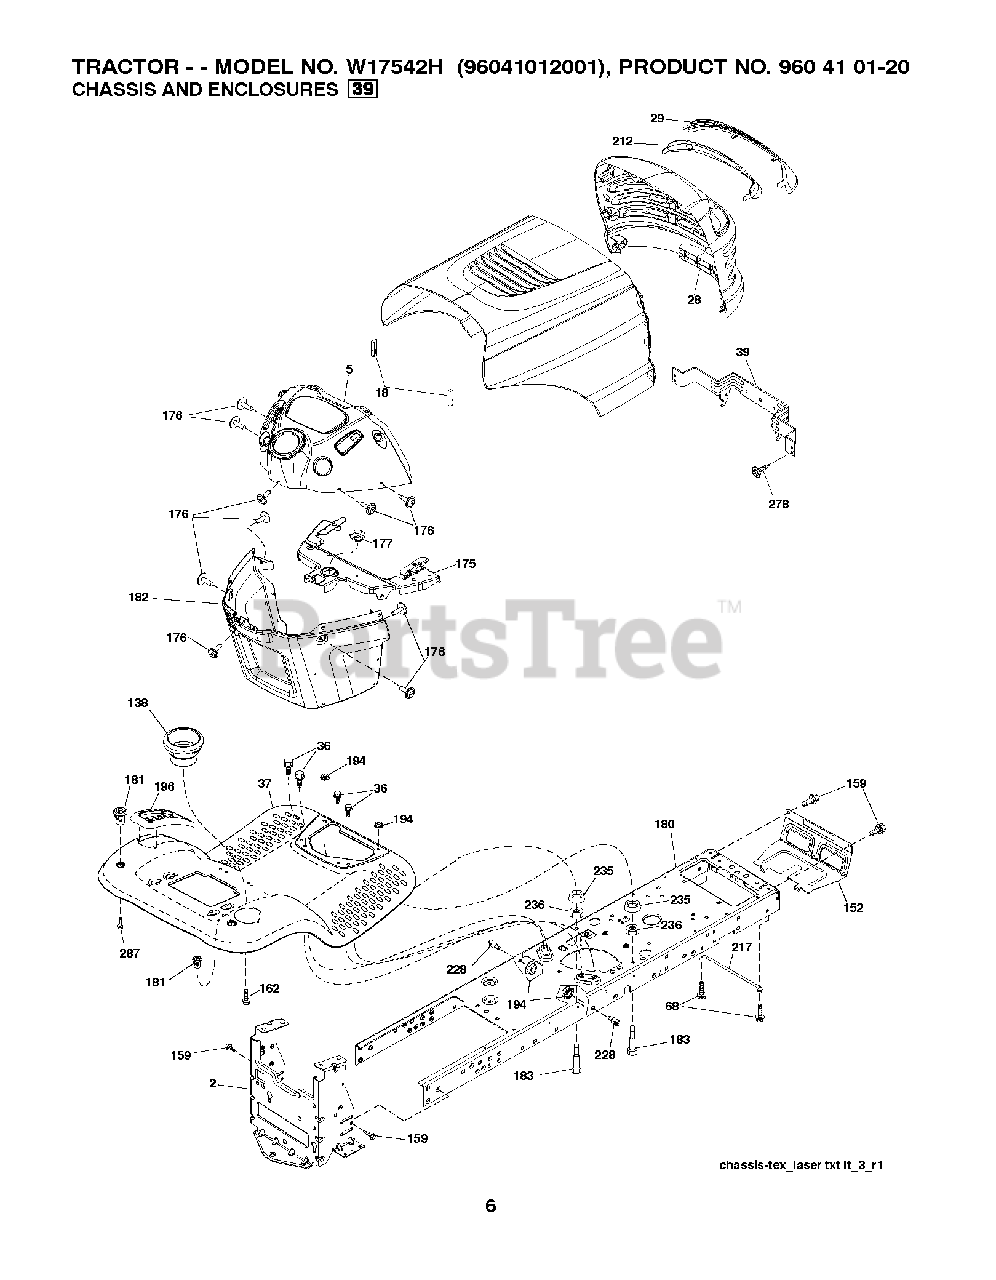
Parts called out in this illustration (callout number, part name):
2	DRAWBAR.1PC.NSTL
5	DASH.P/L.TEX.CBL.CL.N/CHK.BLAC
18	BUMPER.HOOD.LARGE.1.75"
29	LENS.LASER LT.CLEAR.BAR
36	SCREW 5/16"
37	FENDER.TLT.FS.W/CPH.550
39	BRACKET PIVOT
58	DRAWBAR UPPER 2PC SMALL FENDER
68	SCREW LT
138	CUPHOLDER.TL.TEX.BLACK
152	SHIELD.BROWNING/DEBRIS
159	SCREW, 3/8-16X3/4
162	SCREW.HI-LO.CONSOLE
175	CROSSMEMBER.LT
176	SCREW.#10-24X5/8.RN.QU
177	BUSHING STEERING
180	CHASSIS.STAMPING.LT/GT
181	FEND/FTRST.PCH.CPH.NFW
182	DASH.LOWER.LT.CCS
183	BOLT.5/16-18X1-1/4 FULL.THREAD
194	NUT LOCK HEX FLANGE 5/16-18
217	ROD.PIVOT.HOOD
228	STUD.FASTNER.W/ANTI-ROTATE
235	SPACER FENDER
236	NUT.CENTERLOCK.5/16-
278	SCREW.#10 X 0.750.BOS (2 2)
287	SCREW 1/4X20
